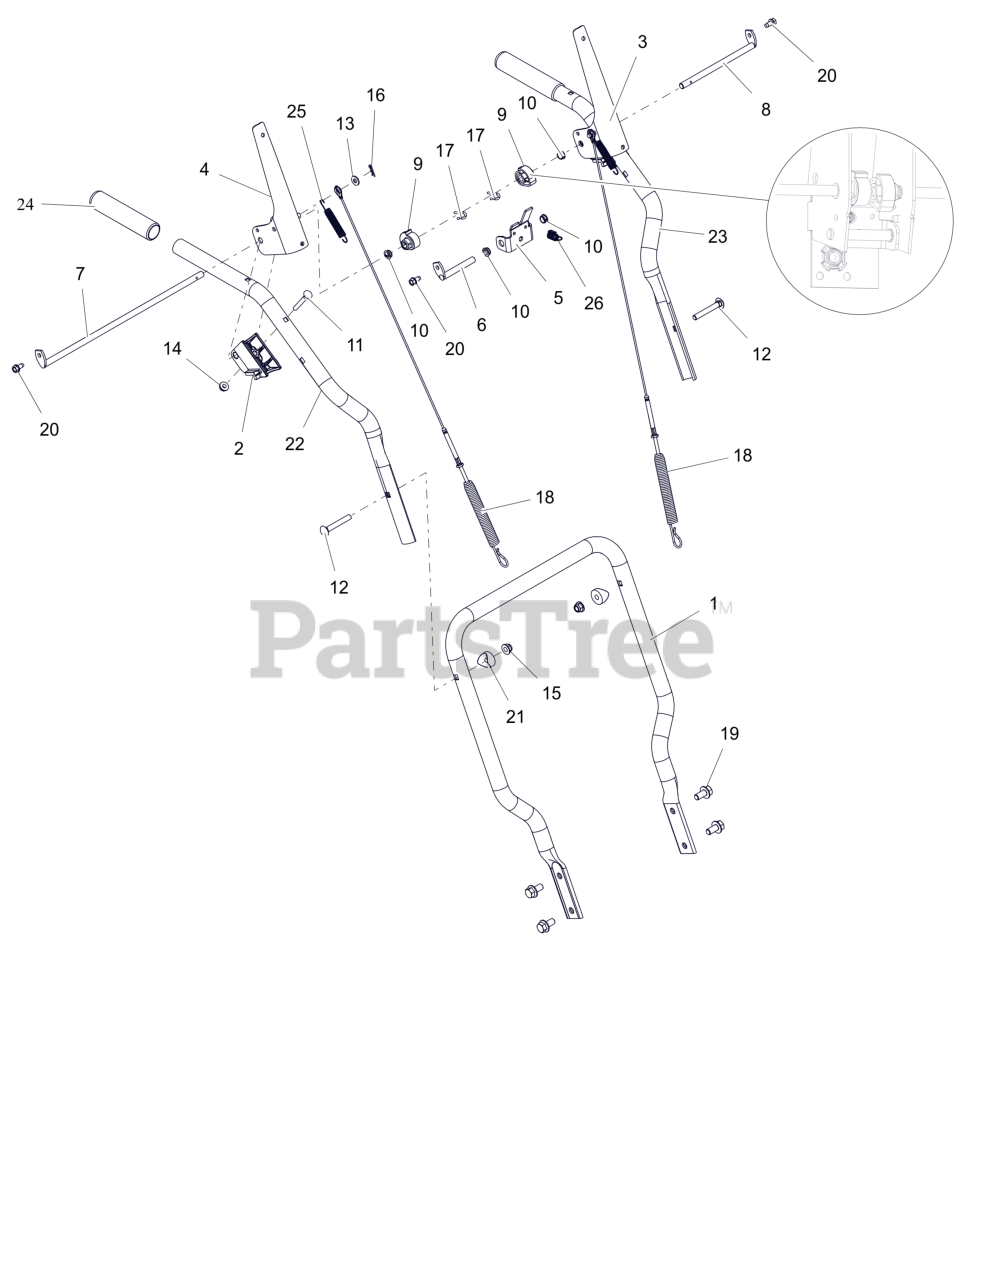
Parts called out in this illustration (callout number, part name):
1	HANDLEBAR, LOWER COMPACT (BLACK)
2	BLOCK, CLUTCH PADDLE
3	LEVER, CLUTCH-LH
4	LEVER, CLUTCH-RH
5	BRACKET, INTERLOCK ARM
6	ROD, PIVOT - INTERLOCK
7	ROD, PADDLE MOUNT - LONG
8	ROD, PADDLE MOUNT - SHORT
9	CAM, INTERLOCK
10	BUSHING, POLYLINER-.38 SNAPIN
11	BLT-RDHDXLSQNK .25-20X2.0 G5YZ
12	BLT-RHSN.31-18X2.25 G5 TBZ 120
13	WSHR,FLT .281X.625X.065 ZCC
14	NUT-LK-CTR-FLG .25-20 ZC120
15	NUT-NYL-FLG.31-18 GF TBZ 120WR
16	PIN, HAIR #178 .06X.77 ZCC
17	PIN, SPRING CLIP
18	CABLE, AUGER & UPPER TRACTION
20	SCR-TAP .25-20X.50 HWH ZCC
21	SPACER, HANDLEBAR
22	HANDLEBAR, UPPER - RH (BLACK)
23	HANDLEBAR, UPPER - LH (BLACK)
24	GRIP, HANDLEBAR
25	SPRING, EXTENSION
26	SPRING-EXT .047X.438X1.45
